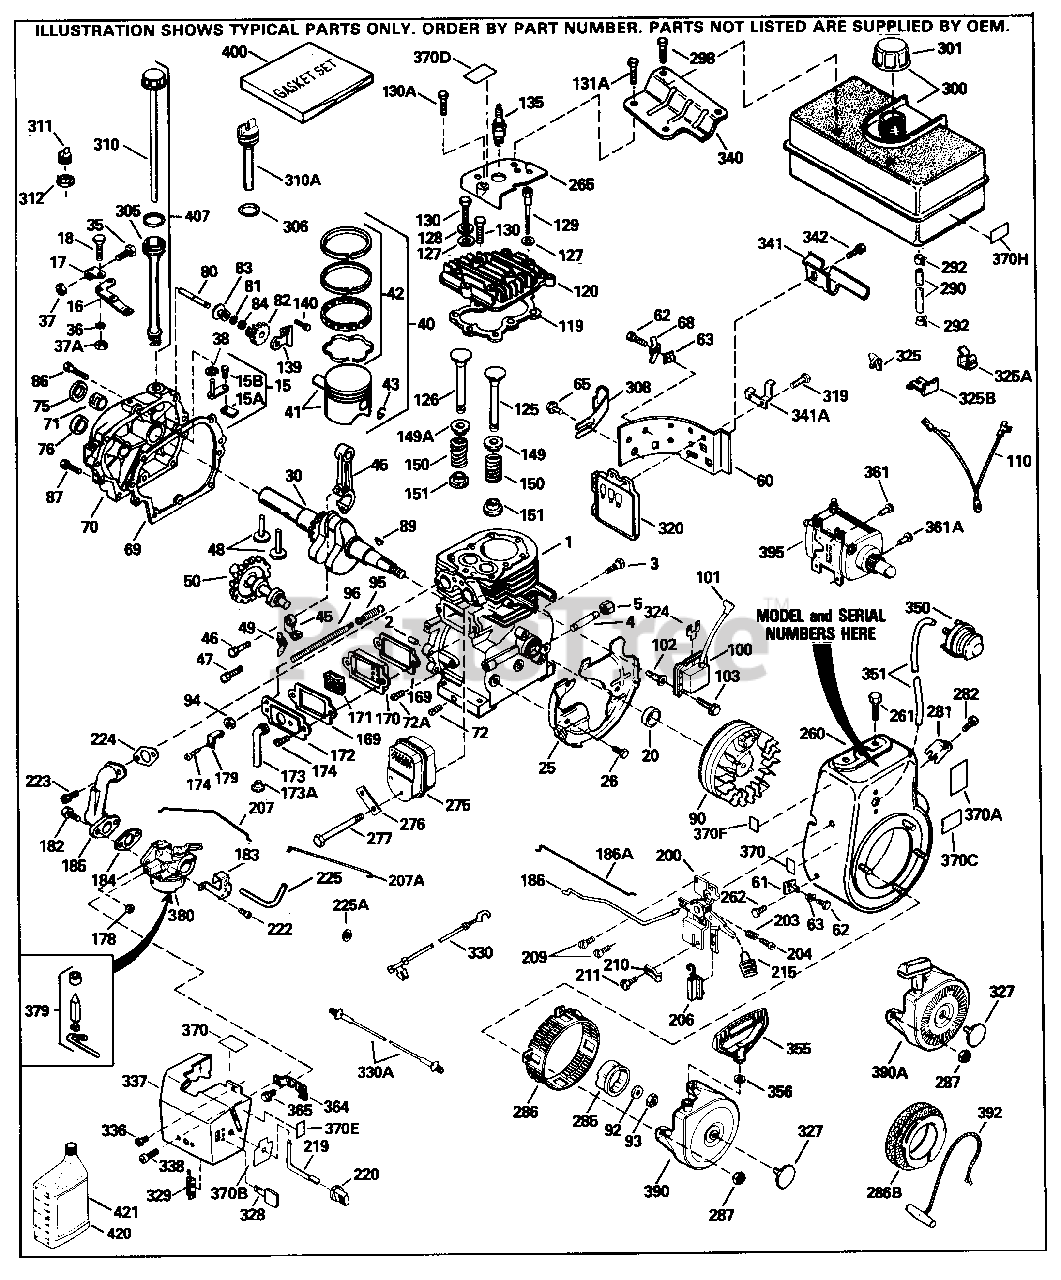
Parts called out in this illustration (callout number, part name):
1	"Cylinder Ass'y. (Incl. 2, 20, 72 & 72 A) (3-1/8" Bore) Bore)
2	Dowel Pin
15	Rod Assy., Governor (Incl. 15A & 15B)
15A	Yoke, Governor
15B	Screw, 6-40 x 5/16"
16	Governor Lever Assy.
17	Governor Lever Clamp
18	Screw, 8-32 x 5/16"
20	Oil Seal
25	Baffle, Blower housing
26	Screw, 1/4-20 x 5/8"
30	Crankshaft
35	Screw, 10-32 x 3/4"
36	Lock Washer #8
37	Lock Nut, 10-32
37A	Lock Nut, 8-32
38	Retaining Ring
40	Piston, Pin & Ring Set (Std.) 3-1/8" Bore
40	Piston, Pin & Ring Set (.010" OS)
40	Piston, Pin & Ring Set (.020" OS)
41	Piston & Pin Ass'y. (3-1/8")(Std.) In cl. 43
41	Piston & Pin Ass'y. (.010" OS) Incl. 43
41	Piston & Pin Ass'y. (.020" OS) Incl. 43
42	Ring Set (Std.) (3-1/8" Bore)
42	Ring Set (.010" OS)
42	Ring Set (.020" OS)
43	Piston Pin Retaining Ring
45	Connecting Rod Ass'y. (Incl.46,47,49)
46	Bolt, Connecting rod
47	Bolt, Connecting rod
48	Lifter, Valve
49	Oil Dipper
50	Camshaft (MCR)
60	Extension, Blower housing
65	Screw, 10-24 x 1/2"
68	Terminal, Ground
69	* Gasket, Cylinder cover
70	Cylinder Cover (Incl. 71, 75 & 80) 31 2)
71	Crankshaft Bushing
72	Oil Drain Plug (Sq. hd., 1/4-18)
75	Oil Seal
80	Shaft, Mechanical governor
81	Washer, Flat
82	Governor Gear Ass'y. (Incl. 81)
83	Spool, Governor
84	Retaining Ring
86	Screw, 1/4-20 x 1-3/16"
87	Screw, 1/4-20 x 1-11/16"
89	Key, Flywheel
90	Flywheel
92	Washer, Belleville
93	Hex Nut, 5/8-18
94	Nut Lock, 10-32
95	Spring, Extension
96	Bolt, Governor spring adjusting
100	Solid State Ignition
102	Stud, Lamination mounting
103	Screw, Torx T-15, 10-24 x 1"
110	Ground Wire
119	* Gasket, Head
120	Head, Cylinder
125	Exhaust Valve (Std.)(Incl. 151)
125	Exhaust Valve (1/32" OS) (Incl. 151)
126	Intake Valve (Std.) (Incl. 151)
126	Intake Valve (1/32" OS) (Incl. 151)
127	Washer Use as req., but not w/6021A s crew
128	Washer, Belleville
129	Screw, 5/16-18 x 1-3/4" Use as requir ed
130	Screw, 5/16-18 x 2" (Use as required)
130A	Screw, 5/16-18 x 1-1/2" Use as req.,b ut not w/650691 washer
131A	Screw, 5/16-18 x 5/8" Use as require d
139	Bracket, Governor gear
140	Screw, 10-24 x 1/2"
149	Valve Spring Cap
149A	Valve Spring Cap
149A	Seal Assy., Intake valve
150	Valve Spring
151	Cap, Lower valve spring
169	* Gasket, Breather cover
170	Breather Body
171	Breather Element
172	Valve Cover
173	Breather Tube
178	Nut & Lock Washer 1/4-28
182	Screw, 1/4-28 x 1"
184	* Gasket, Carburetor
185	Pipe, Intake
203	Spring, Compression
204	Screw, 5-40 x 7/16"
206	Terminal Assy. (Use as required)
207	Link, Governor-to-throttle
209	Screw, 10-32 x 1/2"
223	Screw, Torx T-30, 5/16-18 x 1-1/8"
224	* Gasket, Intake pipe
242	Bracket, Air cleaner
260	Blower Housing (For electric starter)
261	Screw, 5/16-18 x 3/4"
262	Screw, T-40, 5/16-24 x 21/32"
265	Cover, Cylinder head
276	Muffler (Incl. 276)
281	Cover, Starter bubble
282	Screw, 8-32 x 3/8"
285	Cup, Starter
286	Starter Screen (Stationary)
287	Nut & Lock Washer 1/4-28
290	Fuel Line (Braided 16") (41 cm)
292	Fuel Line Clamp
298	Screw, 1/4-15 x 7/8"
300	Fuel Tank (Incl. 292 & 301) NOTE: The se tanks were builtwith different siz e fuel inlet openings. Tanks with the 1-3/16" I.D. opening use fuel cap 34 210. Tanks with the 1-1/2" I.D. openi ng use fuel cap 35355.
301	Fuel Cap (Red)
305	Oil Fill Tube
306	* Gasket, Oil fill
310A	Dipstick (Incl. 306)
325	Clip, Ground wire (Use as required)
325B	Wire Clip
327	Starter Plug
329	Terminal Assy.
330	Wire Harness (6-3/4") (7 Amp)
342	Screw, T-30, 1/4-20 x 1/2"
342	Screw, 1/4-20 x 5/8"
370	Decal, Instruction
370	Decal - Important Lubrication - SAE 3
370B	Decal, Instruction Can be used on HM8 0 with stamped steel recoil starter.
370J	Decal, Instruction Can be used on HM8 0 with diecast starter.
379	Inlet Needle, Seat & Clip Assy.
380	Carburetor (Incl. 184) (Refer to Divi sion 5, Section A, page A3-14 for bre akdown or Fiche 18A-2, Grid F-7)
390A	Rewind Starter Refer to Division 5, S ection C, page 30 for breakdown or Fi che 18A-2, Grid G-1
400	Gasket Set (Incl. items marked*)
407	Fill Tube & Dipstick Assy. Incl. 306 & 308
420	SAE 30, 4-Cycle Engine Oil (Quart)
421	SAE 5W30 4-Cycle Engine Oil - Quart - Winter
